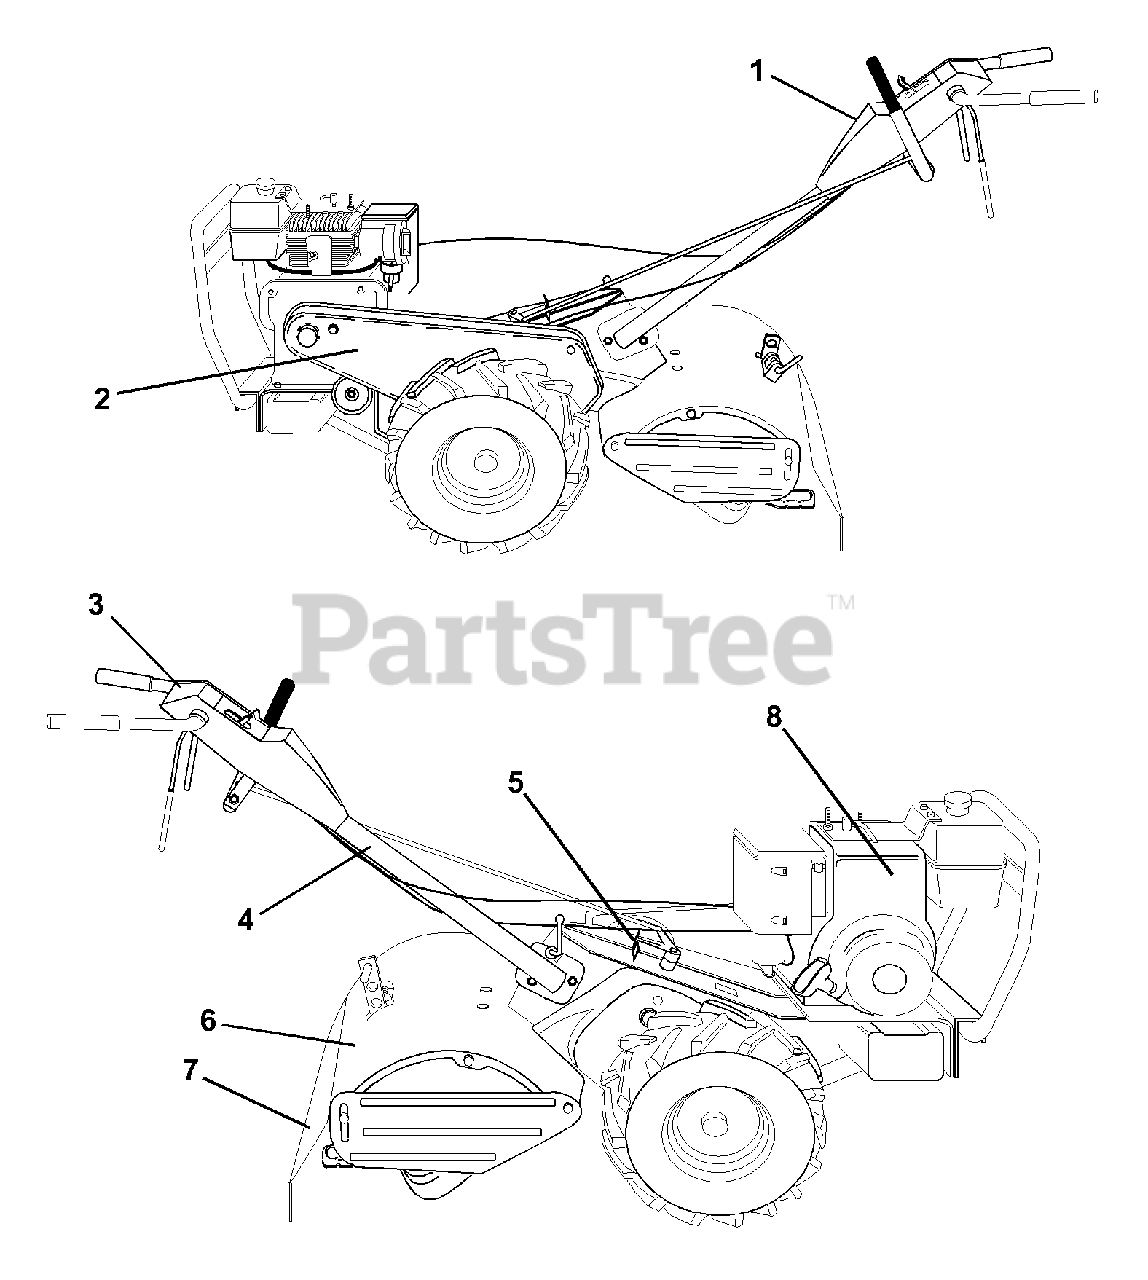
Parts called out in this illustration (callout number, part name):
1	Decal, Logo
2	Decal, Logo
3	Decal, Instruction, Tilling
4	Decal, Hand Placement
5	Decal, Shift Indicator
6	Decal, Caution
7	Decal, Warning, Rotating Tines
8	Decal, Eng. HP
